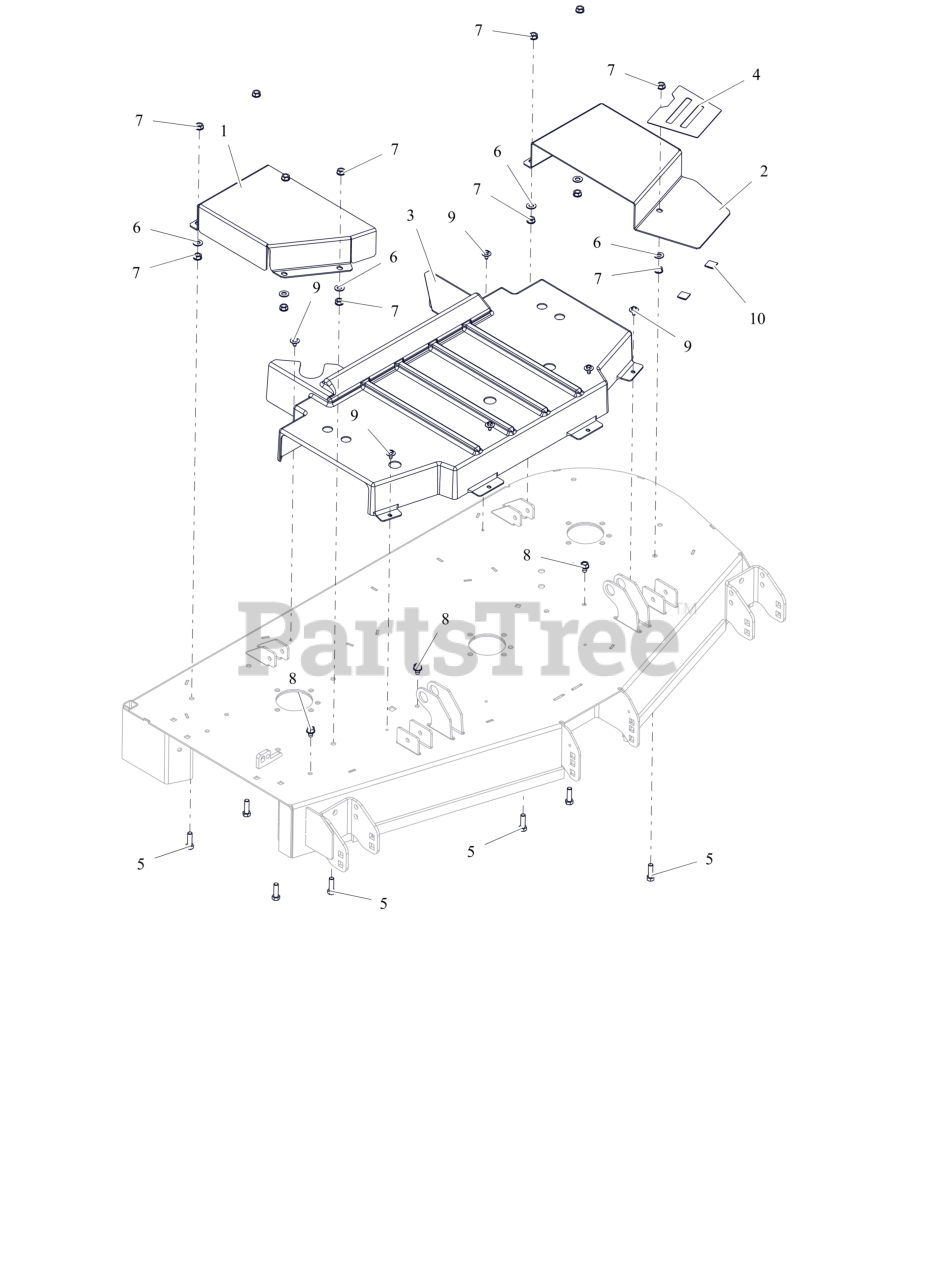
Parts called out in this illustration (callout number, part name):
1	GUARD, BELT 52" RIGHT CE (ORANGE)
2	GUARD, BELT 52" LEFT CE (ORANGE)
3	GUARD,CENTER,DECK SPINDLE CE
4	GRIP TAPE 52-60 BELT COVER
5	BLT, HEX .38-16X1.25 G5 ZCC
6	WSHR,FLT .406X.812X.065 ZCC
7	NUT, SPNLK-FLG .38-16 G5 ZCC
8	SCR,TAP .375-16X.50 HWH TR ZCC
9	SCR, TAP .25-20X.50 LG HWH ZCC
